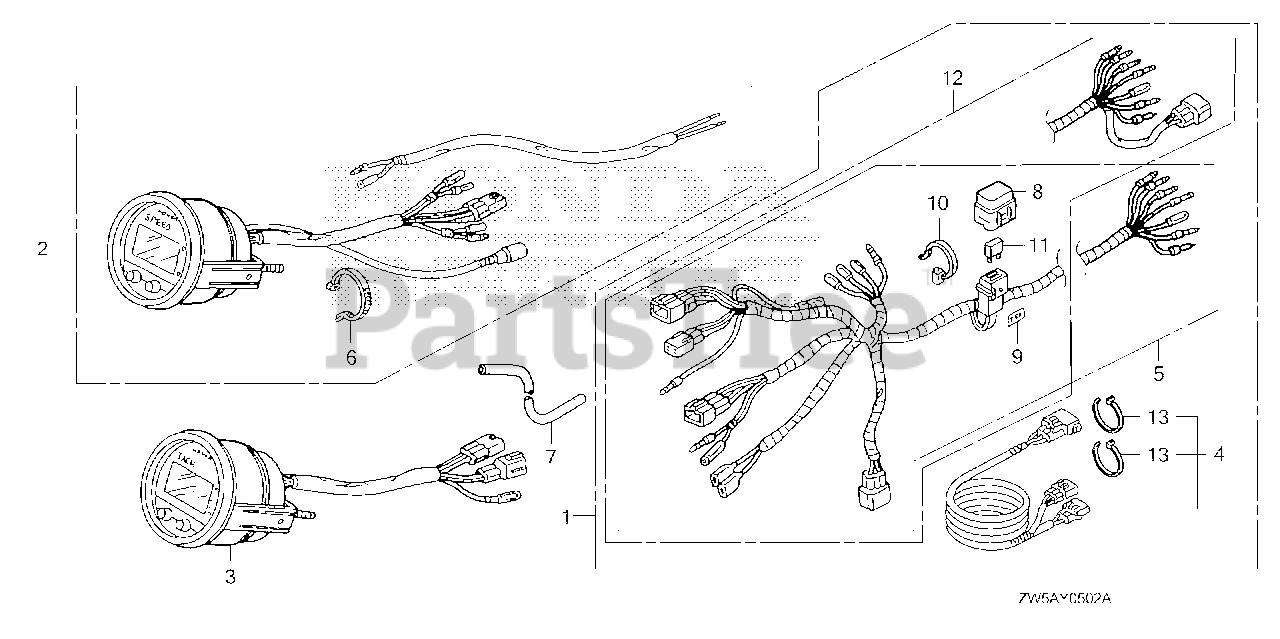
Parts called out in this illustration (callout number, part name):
1	HARNESS KIT, METER (DIGITAL) (INCLUDE 32540-ZY3-801)
1	HARNESS KIT, METER (DIGITAL) (INCLUDE 32540-ZY3-802)
2	SPEEDOMETER KIT (DIGITAL) (FOR 32540-ZY3-800/801)
2	SPEEDOMETER KIT (DIGITAL)(USA)
3	METER KIT, TACHO (DIGITAL) (USA)(USE FOR 32540-ZY3-801) (NOT AVAILABLE)
3	METER KIT, TACHO (DIGITAL)(USA) (NOT AVAILABLE)
4	WIRE ASSY., INDICATOR (DIGITAL)
5	HARNESS ASSY., METER (A)(DIGITAL)
6	BAND (BLACK 3.5X140)
7	TUBE, SPEED METER (4X7X8000)
8	COVER ASSY., FUSE (7.5A)
9	MARK, FUSE (7.5A)
10	TIE, CABLE
11	FUSE, BLADE (7.5A)
12	HARNESS ASSY., METER (A)(DIGITAL)
13	TIE, CABLE (2.4X92) (NATURAL)
